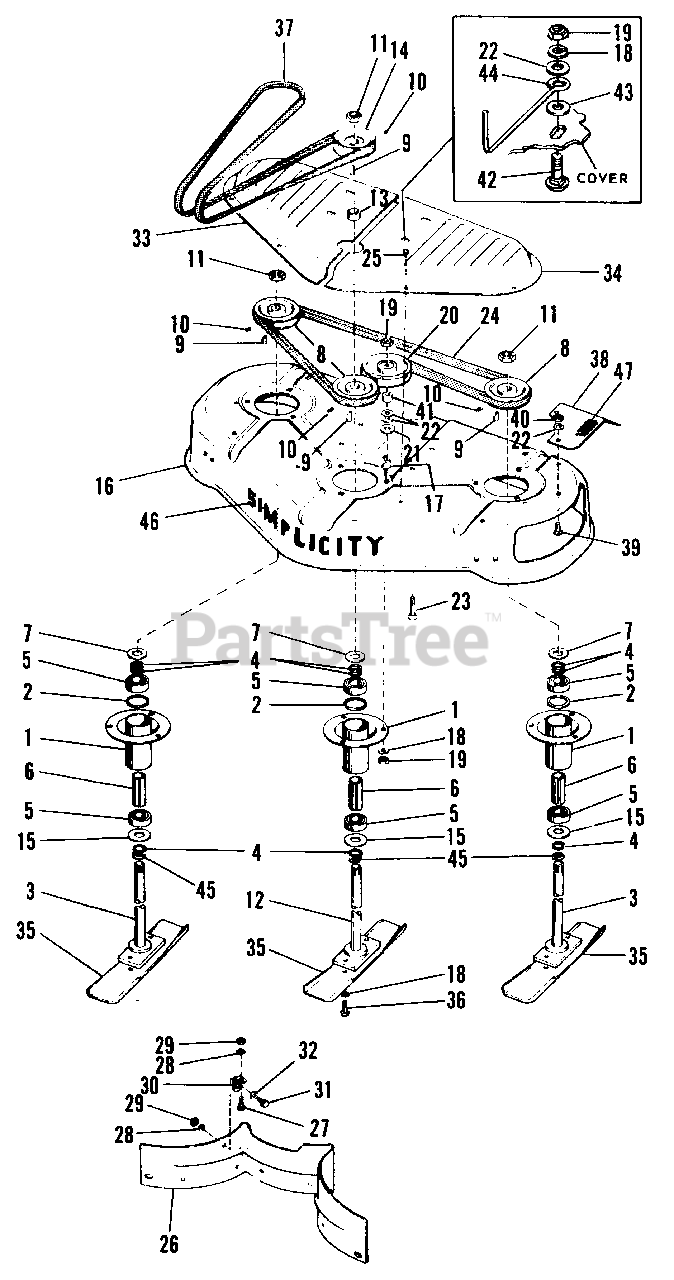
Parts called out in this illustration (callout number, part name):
1	ARBOR TUBE ASSY.
2	RING, Backing
3	ARBOR ASSY.
9	KEY, Woodruff, 3/16 x 5/8
10	SCREW, Set, Socket Hd., Cup Pt., 5/16-18 x 3/8
11	NUT, Hex, Jam, 3/4-16
12	ARBOR DRIVE ASSY.
14	PULLEY, Cross Drive
17	BOLT, Carriage, 3/8-16 x 3/4
18	LOCKWASHER, 3/8
19	NUT, Hex, Full, 3/8-16
20	PULLEY, Idler
22	WASHER, Plain, 5/16
23	BOLT, Carriage, 3/8-16 x 1-3/4
25	SCREW, Self Tapp., Rec. Hex Hd., 1/4-10 x 7/8
26	BAFFLE, Mower
27	SCREW, Self Tapp., Rec. Hex Hd., 1/4-20 x 3/8
28	LOCKWASHER, 1/4
29	NUT, Hex, Full, 1/4-20
30	CLIP, Baffle
31	CAPSCREW, Hex, 1/4-20 x 5/8
32	WASHER, Plain, 1/4
33	COVER, R.H.
34	COVER, L.H.
36	CAPSCREW, Hex Hd., 3/8-16 x 5/8
37	V-BELT, Cross Drive
38	DEFLECTOR
39	BOLT, Carriage, 5/16-18 x 3/4
40	NUT, Hex, Full, 5/16-18
42	BOLT, Carriage, 3/8-16 x 1
43	WASHER, Plain, 7/16
44	STOP, Belt
46	DECAL, Simplicity
47	DECAL, Safety
